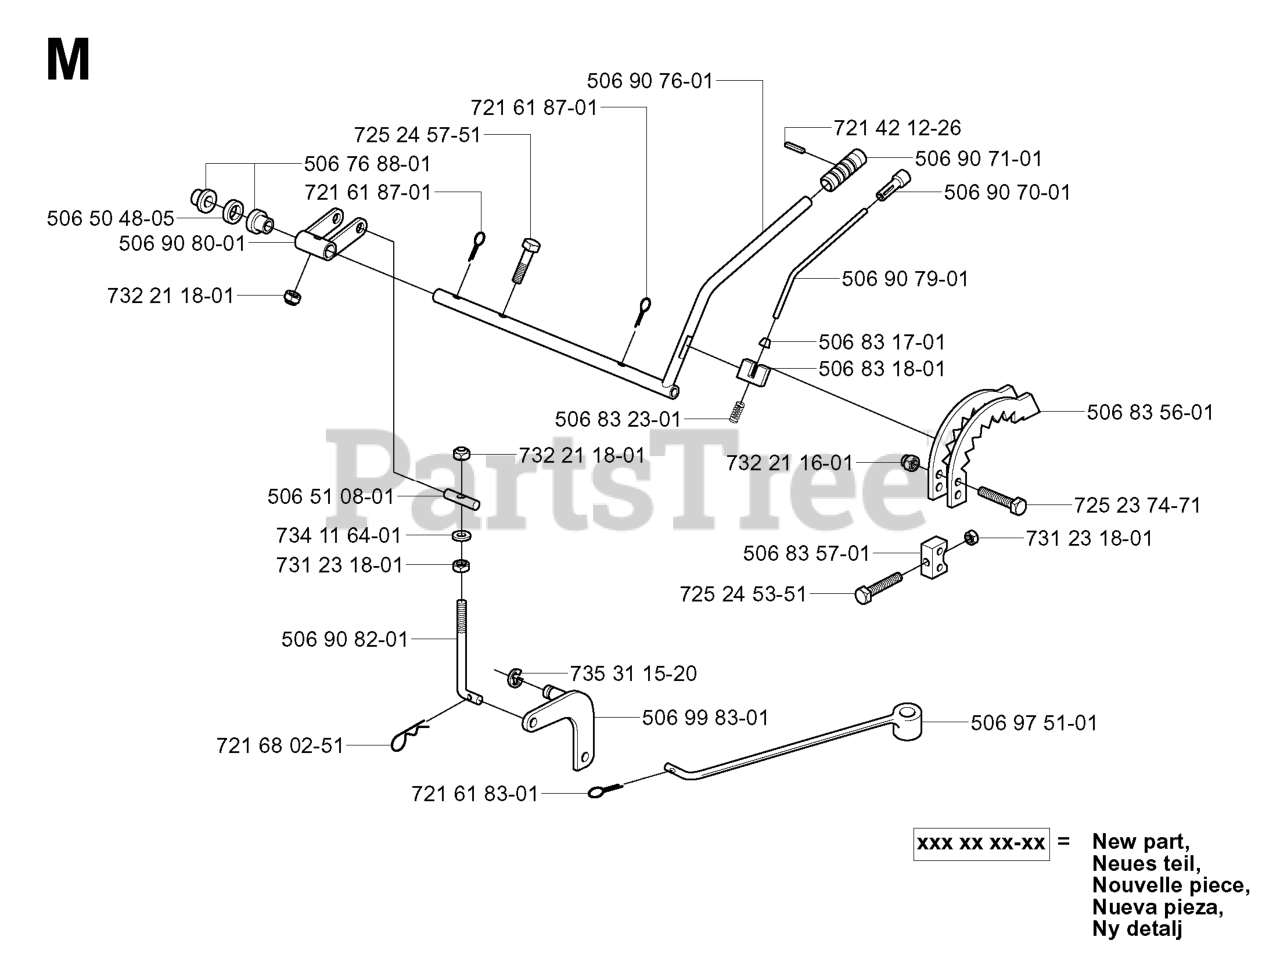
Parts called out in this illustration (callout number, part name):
580	RING, LOWER CHUTE
581	SCREW, 1/4-14X.63 HWATAP
582	CLIP, CHUTE RING PLASTIC
590	CHUTE, LWR SRS 8HP
591	SCREW, 1/4-20X .50 HHC
592	NUT 1/4-20
600	CHUTE, UPR SRS W/O HDLE
601	WIRE, HINGE 6.65 LG SR
603	WASHER, FLAT .344X .69X.
604	KNOB, W/NUT
605	NUT, 5/16-18 REGHEX
607	WASHER, FLAT .344X .69X.
608	NUT, 5/16-18 REGHEXCTRLK
610	BRACKET, WORM ADJUST
612	WASHER, FLAT .344X .69X.
613	WASHER, HVSPTLK .328X.60X
614	NUT, 5/16-18 REGHEX
620	BRACKET, CHUTE
622	WASHER, FLAT .344X .69X.
623	WASHER, HVSPTLK .328X.60X
624	NUT, 5/16-18 REGHEX
625	PLATE, CHUTE ROD
626	SCREW, 1/4-20X .50 HHC
627	NUT, 1/4-20 REGHEXCTRLK
630	ROD, ASSY CHUTE LWR
631	WASHER, FLAT .40X.75X.025
632	PIN, COTTER .090/.086X.75
633	BLOCK, PIVOT PLASTIC
